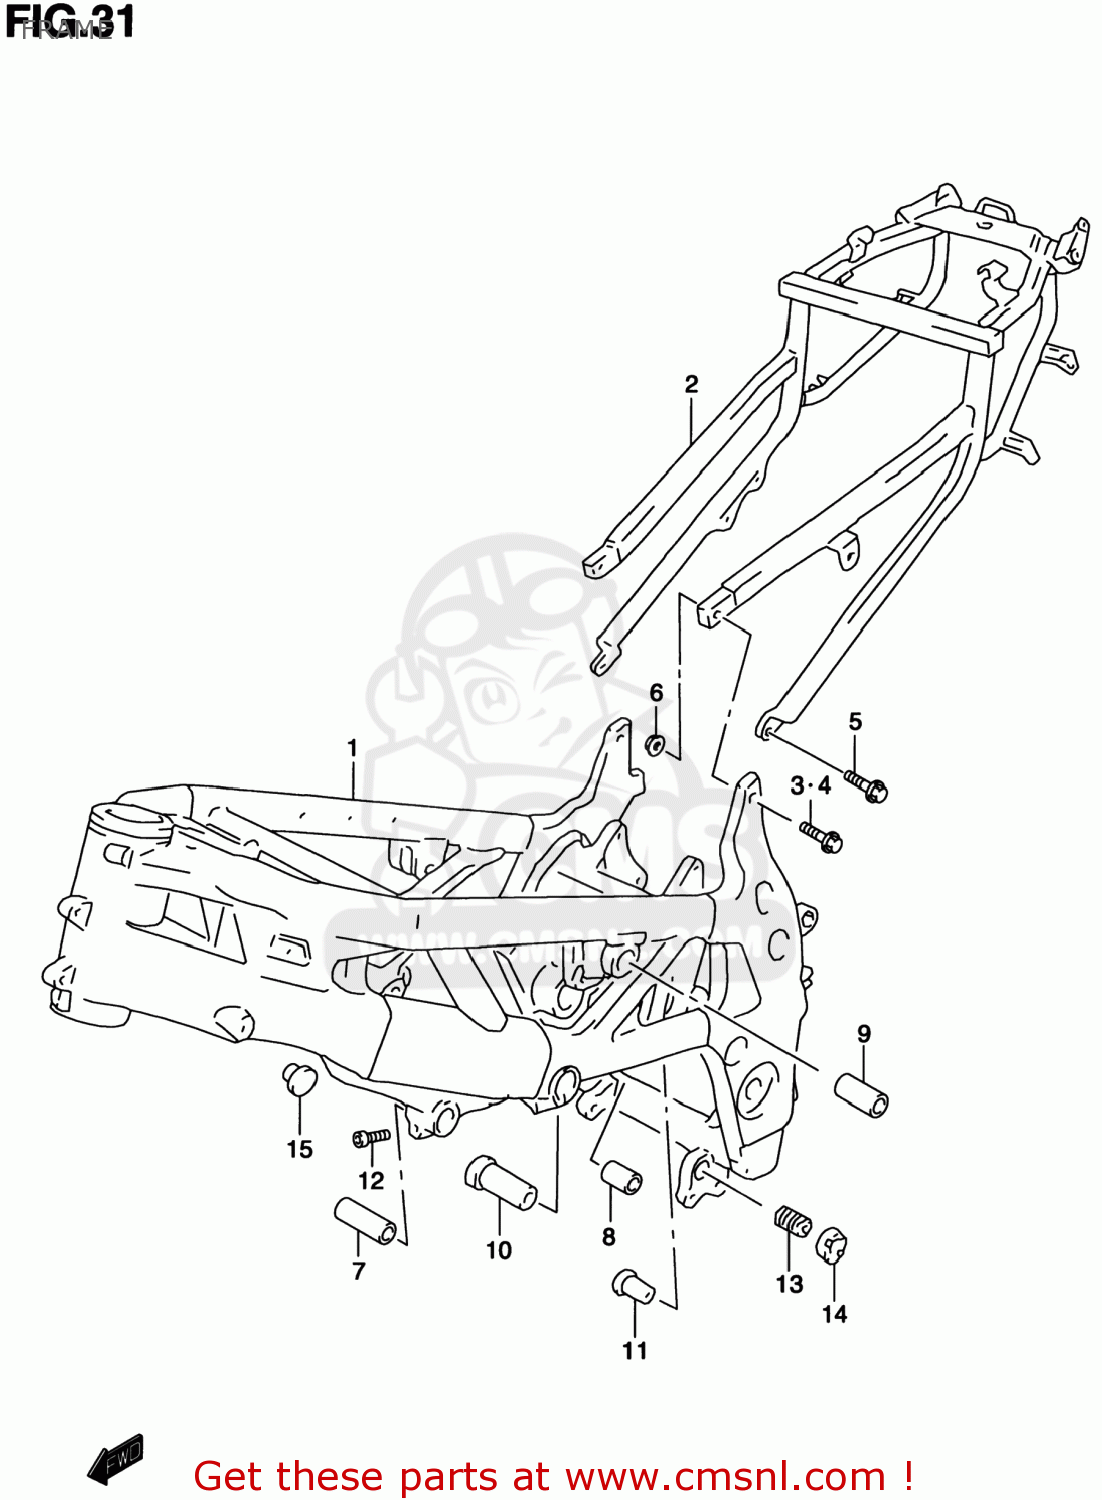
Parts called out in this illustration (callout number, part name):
1	FRAME
2	RAIL,SEAT
3	BOLT(10X30)
4	BOLT(10X45)
5	BOLT(10X30)
6	NUT
7	SPACER,ENG HEAD MTG FR,L
8	SPACER,ENG HEAD MTG RR,R
9	SPACER,ENG HEAD MTG RR,L
10	SPACER,CRANK CASE MTG FR,L
11	SPACER,ENGINE MOUNTING
12	BOLT
13	BOLT,CRANKCASE ADJUST
14	NUT,CRANKCASE ADJUST
15	CAP
